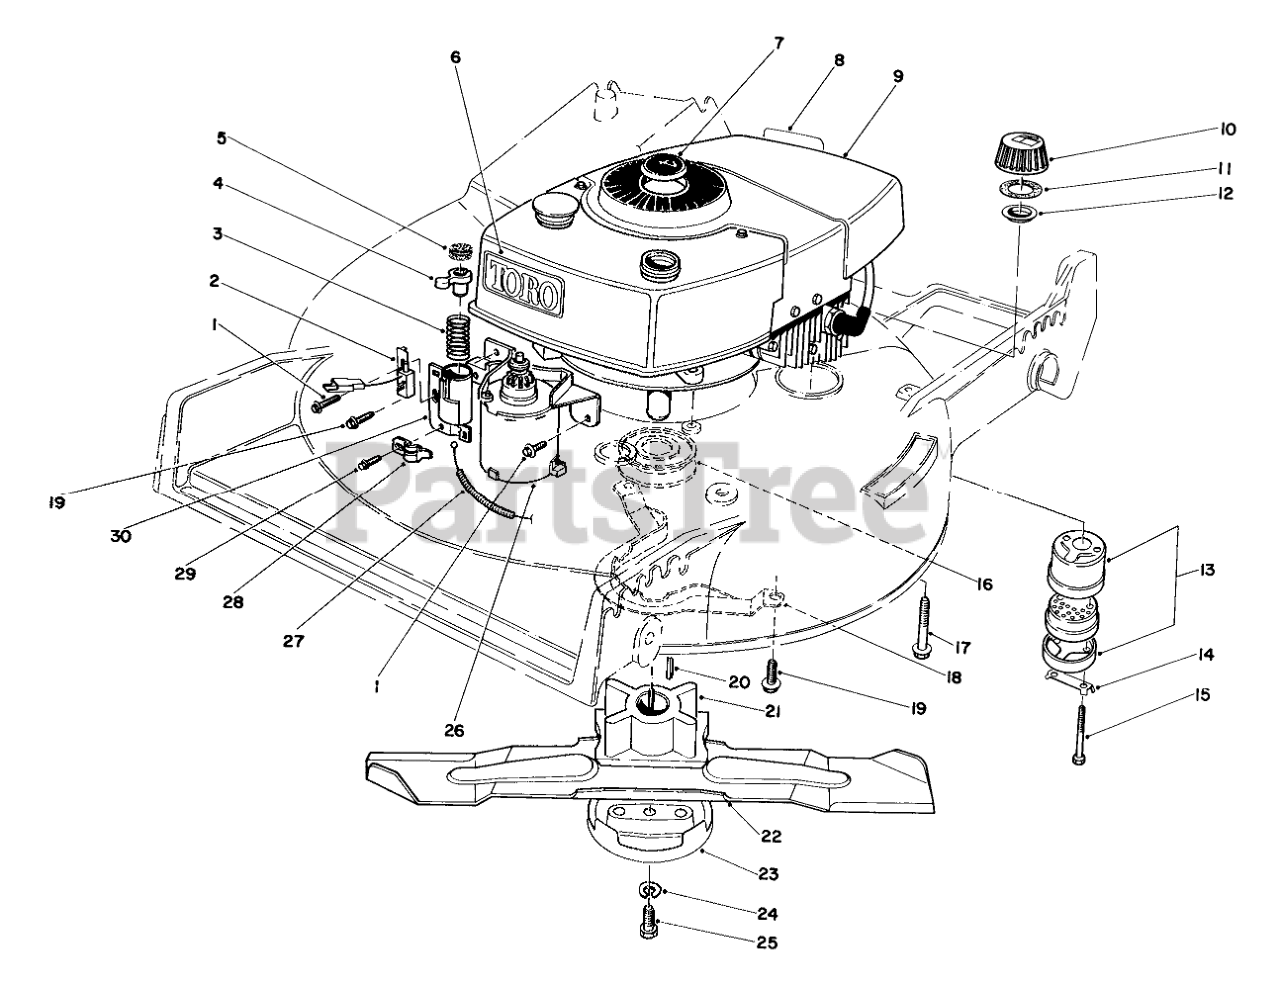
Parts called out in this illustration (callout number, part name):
1	SCREW
2	PUSH BUTTON SWITCH
3	COMPRESSION SPRING
4	Plunger
5	Pad-Friction
6	Decal Tow
7	PLUG BUTTON
8	Decal-Maintenan
9	Engine
10	Gas Cap Assembly (Incl. Ref. #11 8 12)
11	GASKET
12	GAS CAP BAFFLE
13	Muffler Assembly (Incl. Ref. #14 & 15)
14	CLIP - LOCKING
15	SCREW-HH
16	Pulley
17	3/8-16 X 2 CAPSCREW
18	BELT GUIDE
19	Screw
20	KEY-SQUARE
21	BLADE RETAINER(DEEP)
22	BLADE-21in
23	Anti Scalp Cup
24	WASHER-LOCK
25	SCREW-BLADE
26	Starter Motor
27	BRAKE CABLE
28	CABLE CLAMP
29	SCREW
30	TUBE W A
